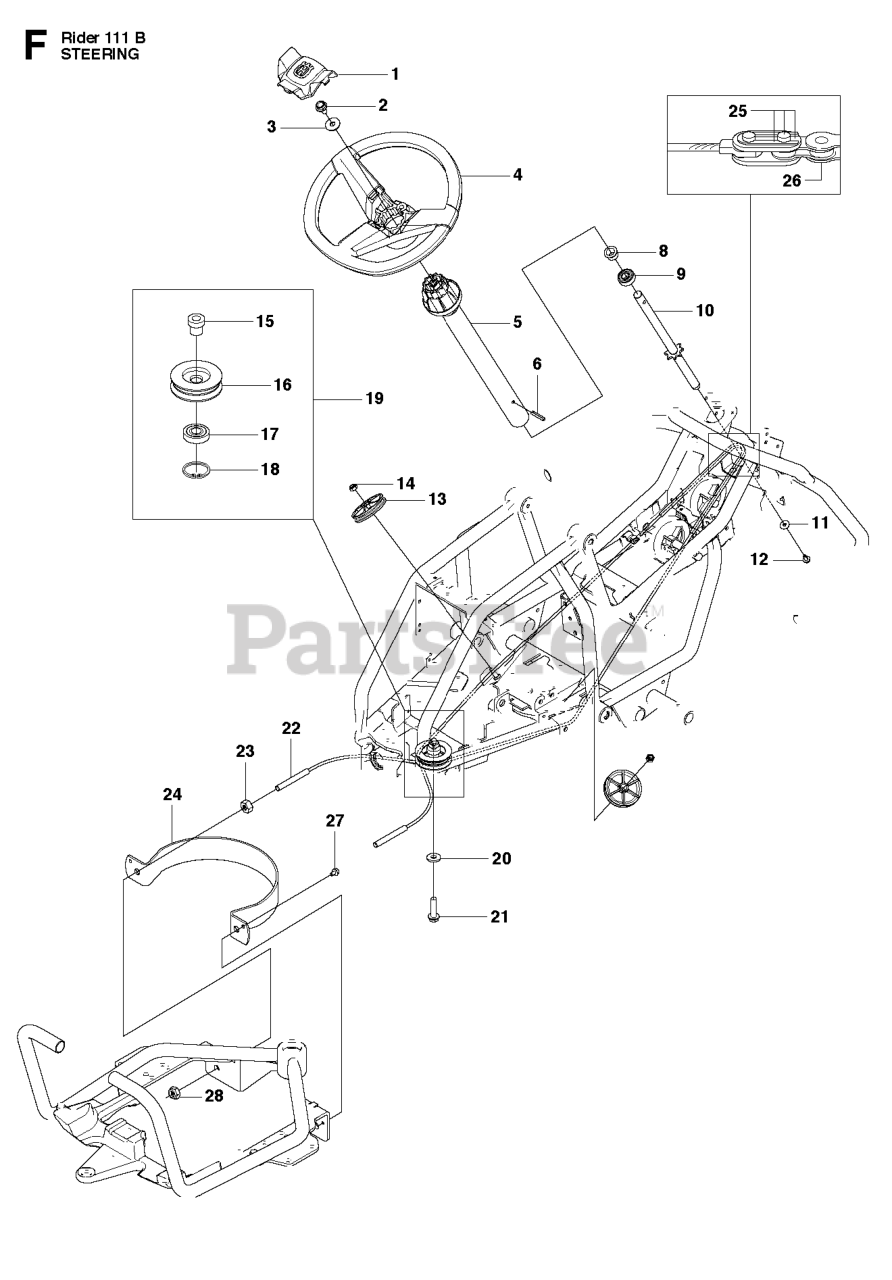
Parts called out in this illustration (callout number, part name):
1	RP INSERT.CAP.WHL.STRG.HUSQ.
4	RP WHEEL.STEER.HUSQ.PREM.OVMLD
9	BALL BEARING 6004-2RS1
10	STEERING ROD
11	WASHER - 26X6.5X1.6
12	SCREW EHHFM
14	LOCKNUT M6
17	BALL-BEARING 6204-2RS
18	CIRCLIP SGH 47
19	STEERING ASSY
22	WIRE ASSY
23	NUT
24	GUIDE RAIL
26	STEERING CHAIN
27	SCREW
28	NUT
